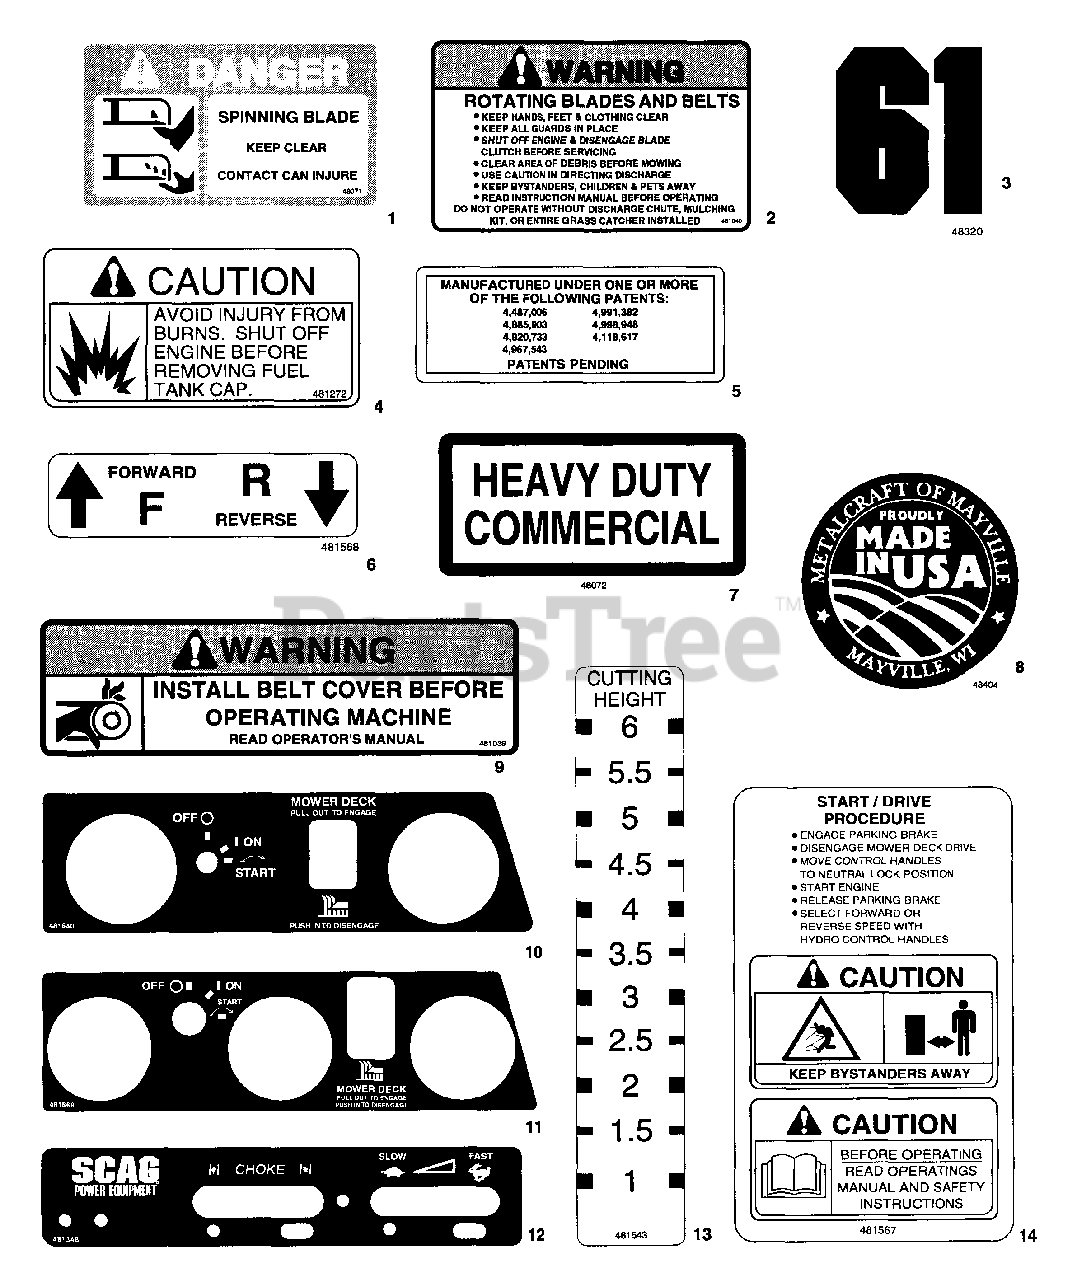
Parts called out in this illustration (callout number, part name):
1	Decal, Danger-Spinning Blades
2	Decal, Warning-Rotating Blades
3	Decal, 52
4	Decal, Fuel Tank
5	Decal, Patents
6	Decal, Traction Control
7	Decal, Heavy Duty Commercial
8	Decal, Metal Craft-Made In USA
9	Decal, Belt Cover
10	Decal, Instrument Panel-Upper
11	Decal, Instrument Panel-Upper (Kawasaki)
12	Decal, Instrument Panel-Lower
13	Decal, Cutting Height
14	Decal, Start/Drive Procedure
